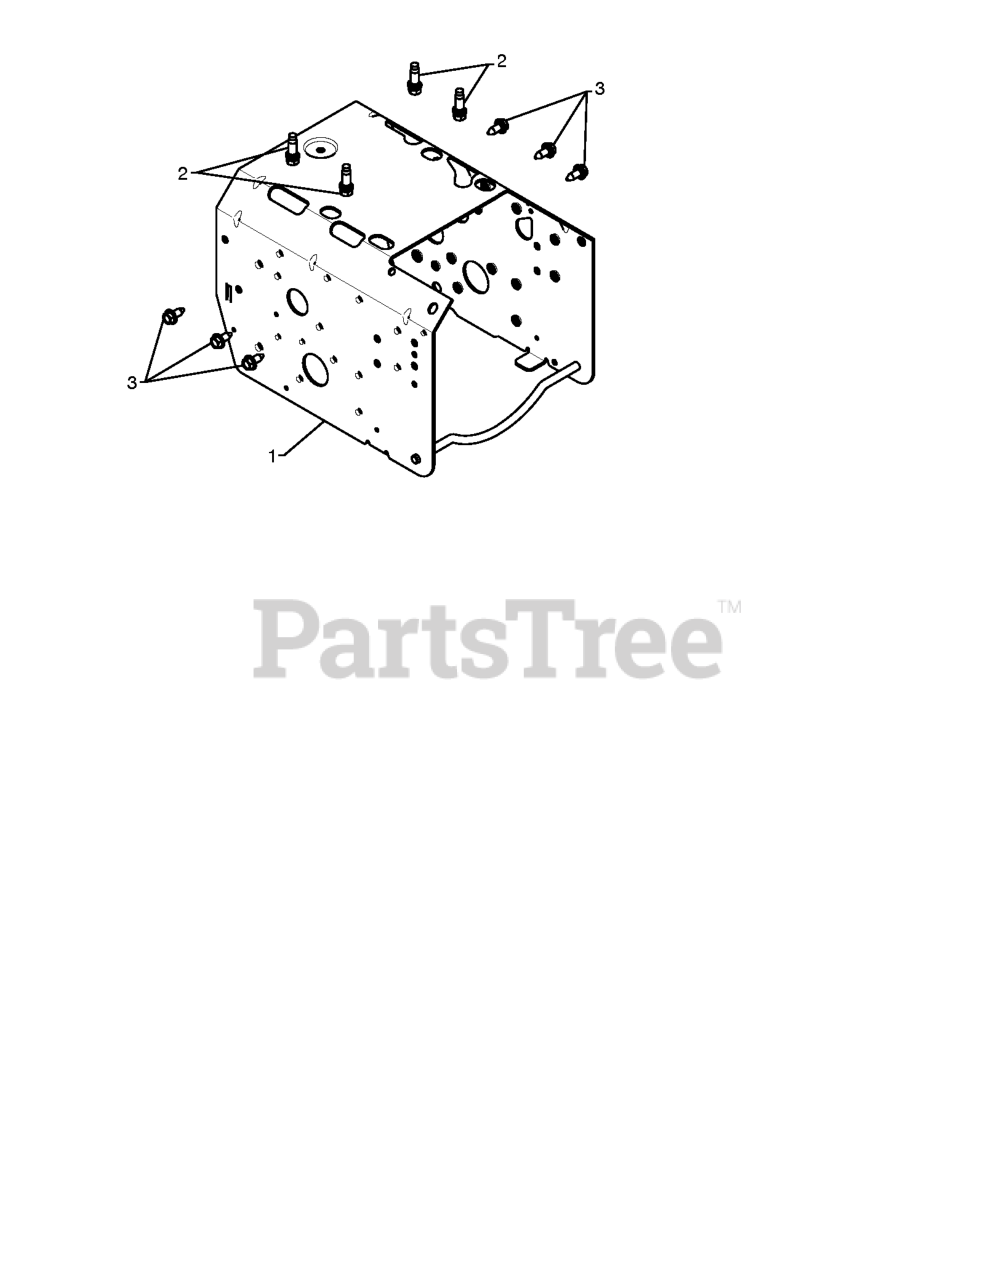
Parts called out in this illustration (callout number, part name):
1	FRAME.WELD.PNT.GEAR.ORANGE
2	BOLT 3/8-16X1-1/8
3	BOLT.HEX.HD.WASHER.5/16-18X.75
